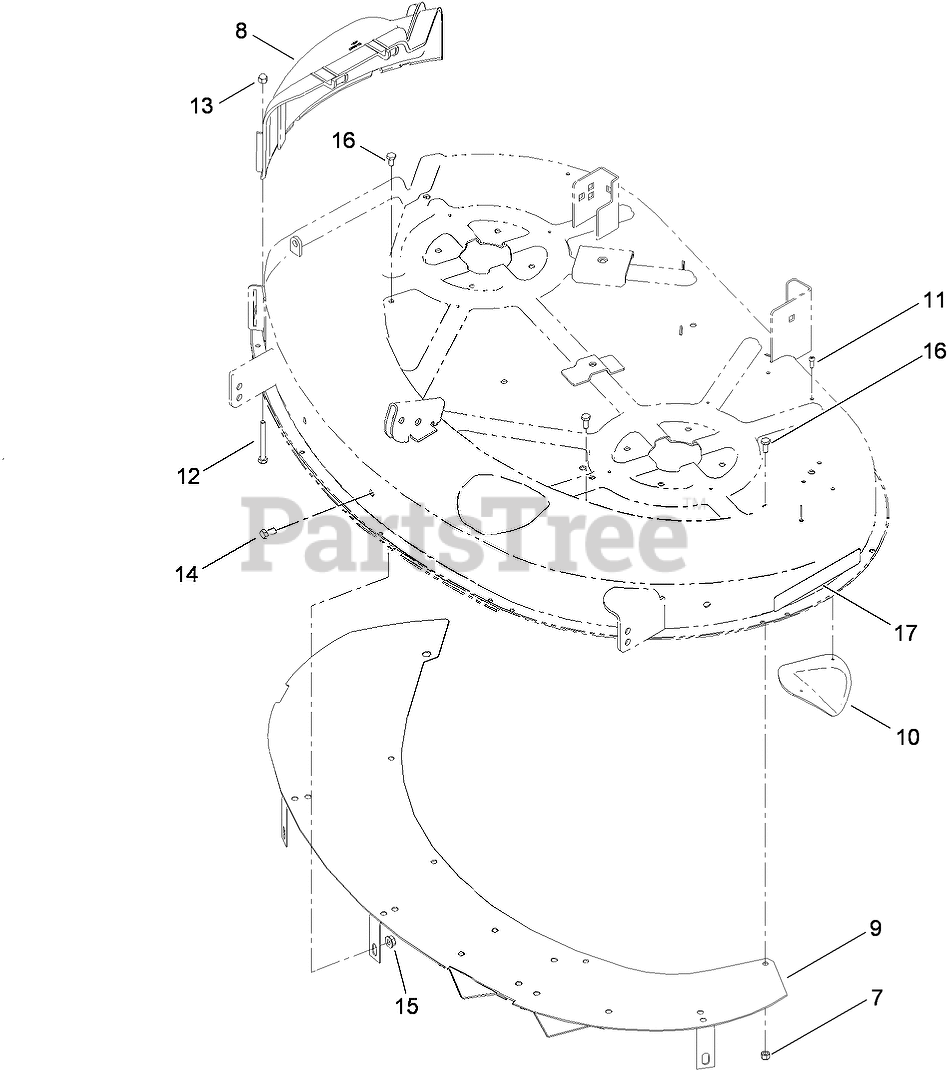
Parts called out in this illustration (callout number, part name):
7	NUT-LOCK, NI
8	COVER-DISCHARGE
9	BAFFLE UPPER ASM
10	PLATE-KICKER
11	SCREW-PPH
12	SCREW-HH
13	NUT-CAP
14	SCREW-HH
15	NUT-HF
16	SCREW-HH
17	DECAL-RECYCLER
